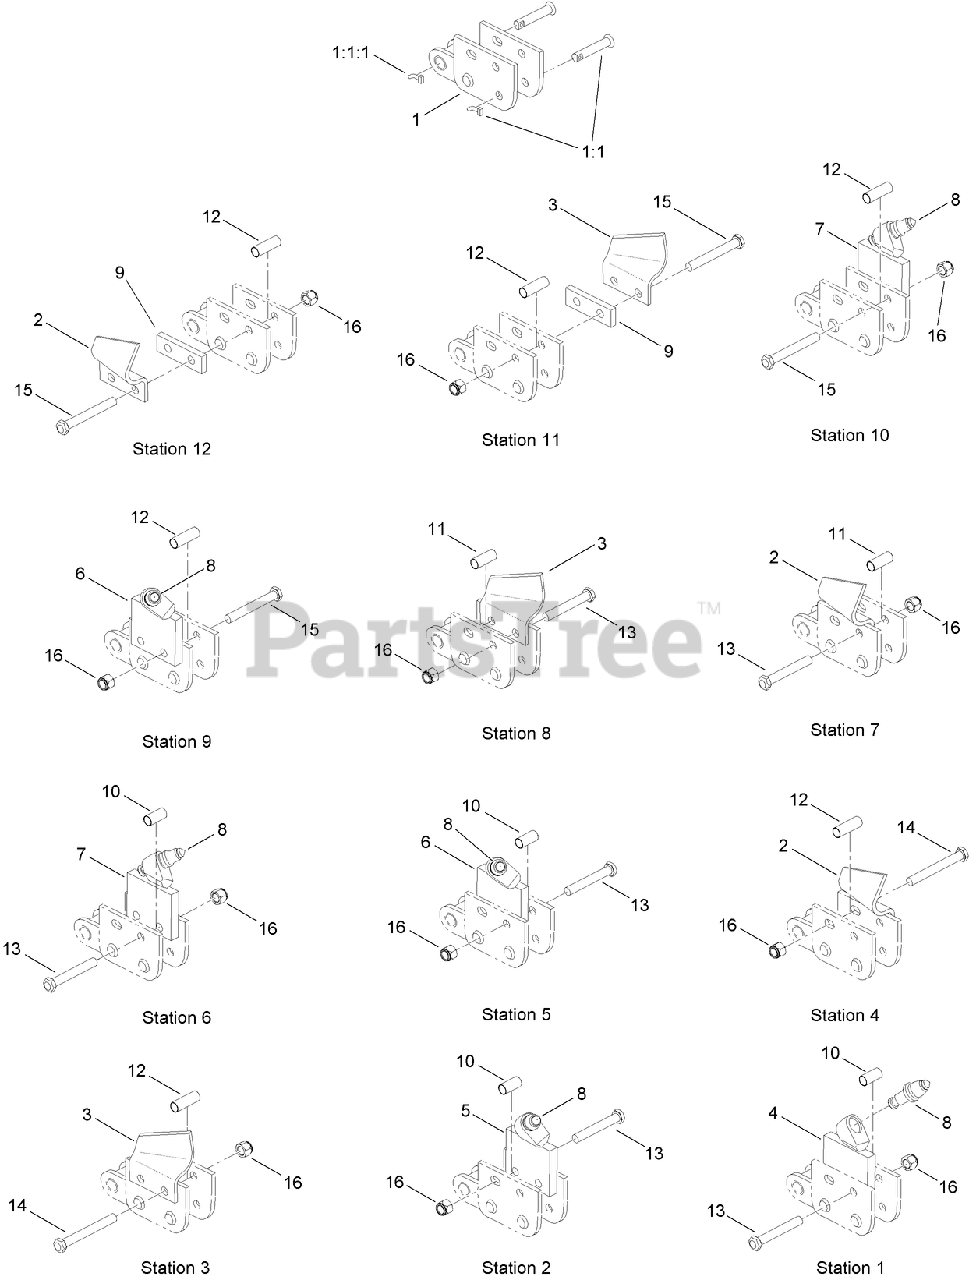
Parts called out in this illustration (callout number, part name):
1	CHAIN REPAIR LINK ASM
1:1	NOTCHED PIN AND KEEPER ASM
1:1:1	PIN-KEEPER
2	CUTTER-CUP, RH
3	CUTTER-CUP, LH
4	HOLDER-BIT, RH CENTER
5	HOLDER-BIT, LH CENTER
6	HOLDER-BIT, RH
7	HOLDER-BIT, LH
8	BIT-CARBIDE, FULL CAB
9	SPACER-FLAT
10	SPACER-TUBE, INSIDE ADAPTER
11	SPACER-TUBE, INSIDE CUP
12	SPACER-TUBE, OUTSIDE MOUNT
13	BOLT-HH
14	BOLT-HH
15	BOLT-HH
16	NUT-LOCK
